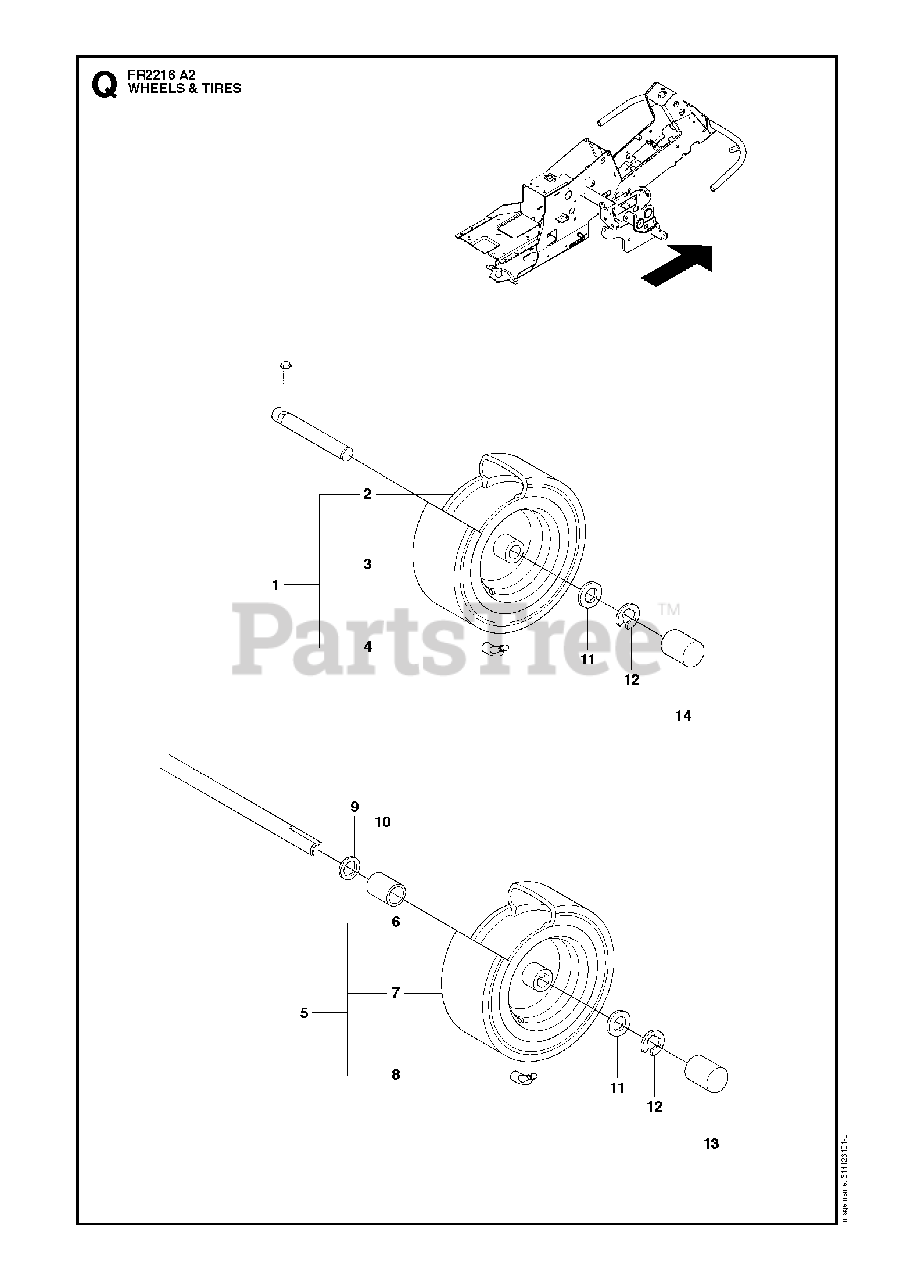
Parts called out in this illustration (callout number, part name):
6	RP RIM
10	SPACE SLEEVE
12	RETAINING RING
